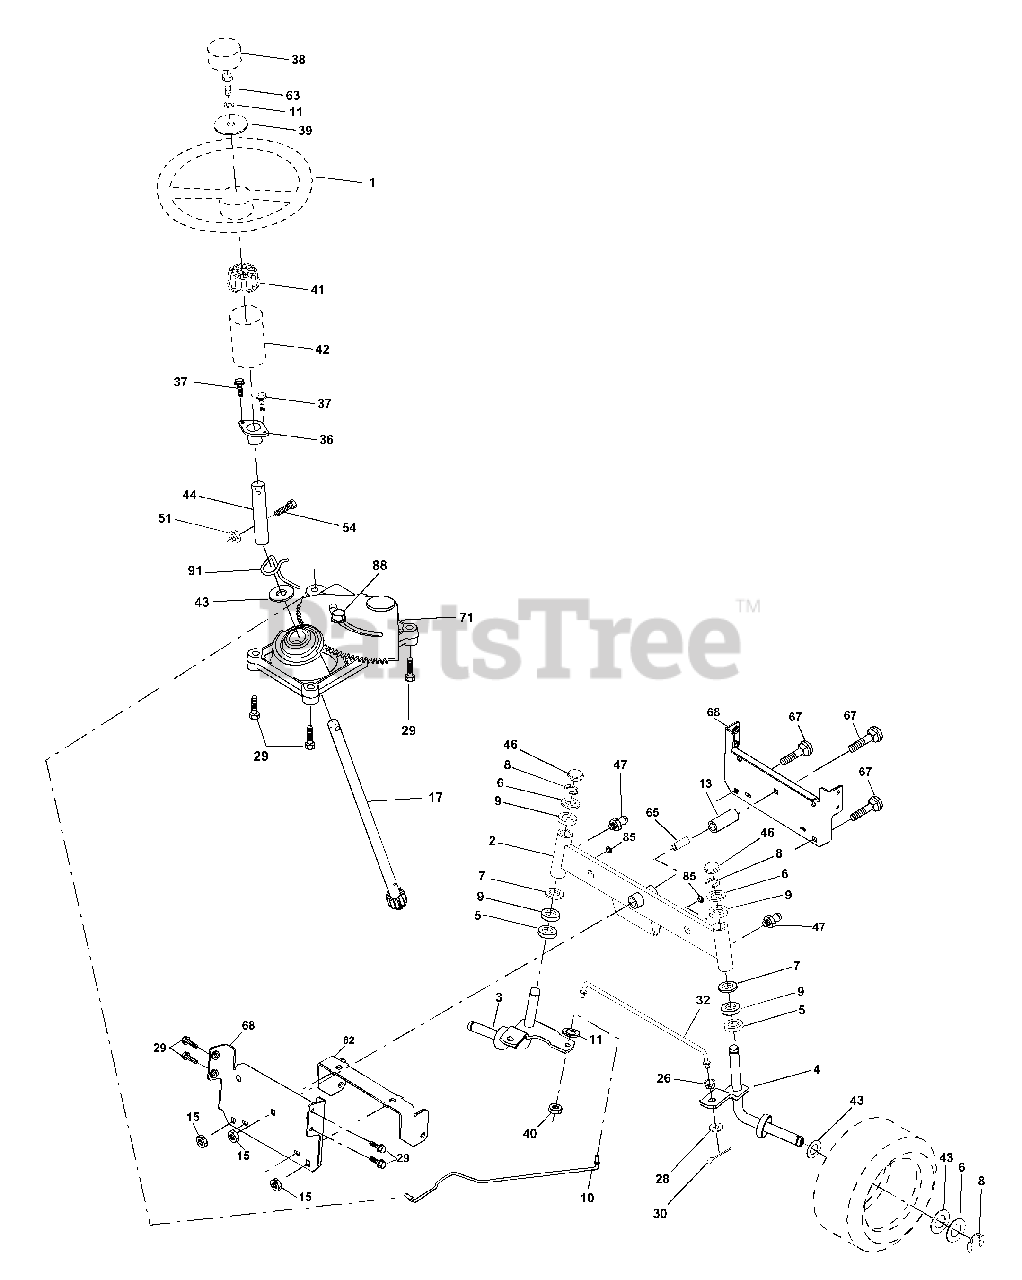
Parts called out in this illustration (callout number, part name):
1	Wheel Steering
2	Axle Asm STMP Dropped STL
3	Spindle Asm LH
4	Spindle Asm RH
5	Bearing Race Thrust Harden
6	Washer 25/32 X 1-5/8 X 16 Ga
7	Washer 27/32 X 1-1/4 X 16 Ga
8	Ring Klip #t5304-75
9	Bearing Col Strg Blk
11	Washer Lock Hvy Hlcl Spr 3/8
13	Spacer Brg Axle Front
15	Nut Hex Flange Lock
17	Shaft Asm Strg
26	Bushing Link Drag Blk LR
28	Washer 13/32 X 7/8 X 16 Ga
29	Screw 3/8-16x3/4
30	Pin Cotter 1/8 X 3/4 Cad
32	Rod Tie Wire Form 19 75 Mech
36	Bushing Strg
38	Cap Wheel Steering
39	Washer 13/32 X 2-3/8 X 12 Ga
40	Lock nut
41	Adaptor Wheel Strg
42	Boot Steering Shaft
43	Washer 25/32 X 1 1/4 X 16 Ga
44	Extension Steering Shaft LR/LT
46	Cap Spindle Fr Top Blk
47	Fitting Grease
51	Nut Lock Hex w/Ins 5/16-18
54	Bolt Fin Hex 5/16-18 Unc x 1-1/4
63	Bolt Fin Hex 3/8-16unc x 1 Gr. 5
65	Spacer Brace Axle
67	Bolt Rdhd Sq 3/8-16 x 2-1/4
68	Axle, Brace
71	Steering Asm
82	Bracket Susp Chassis Front
85	Fastner Christmas Tree
88	Bolt Shoulder 7/16-20
91	Clip Steering
